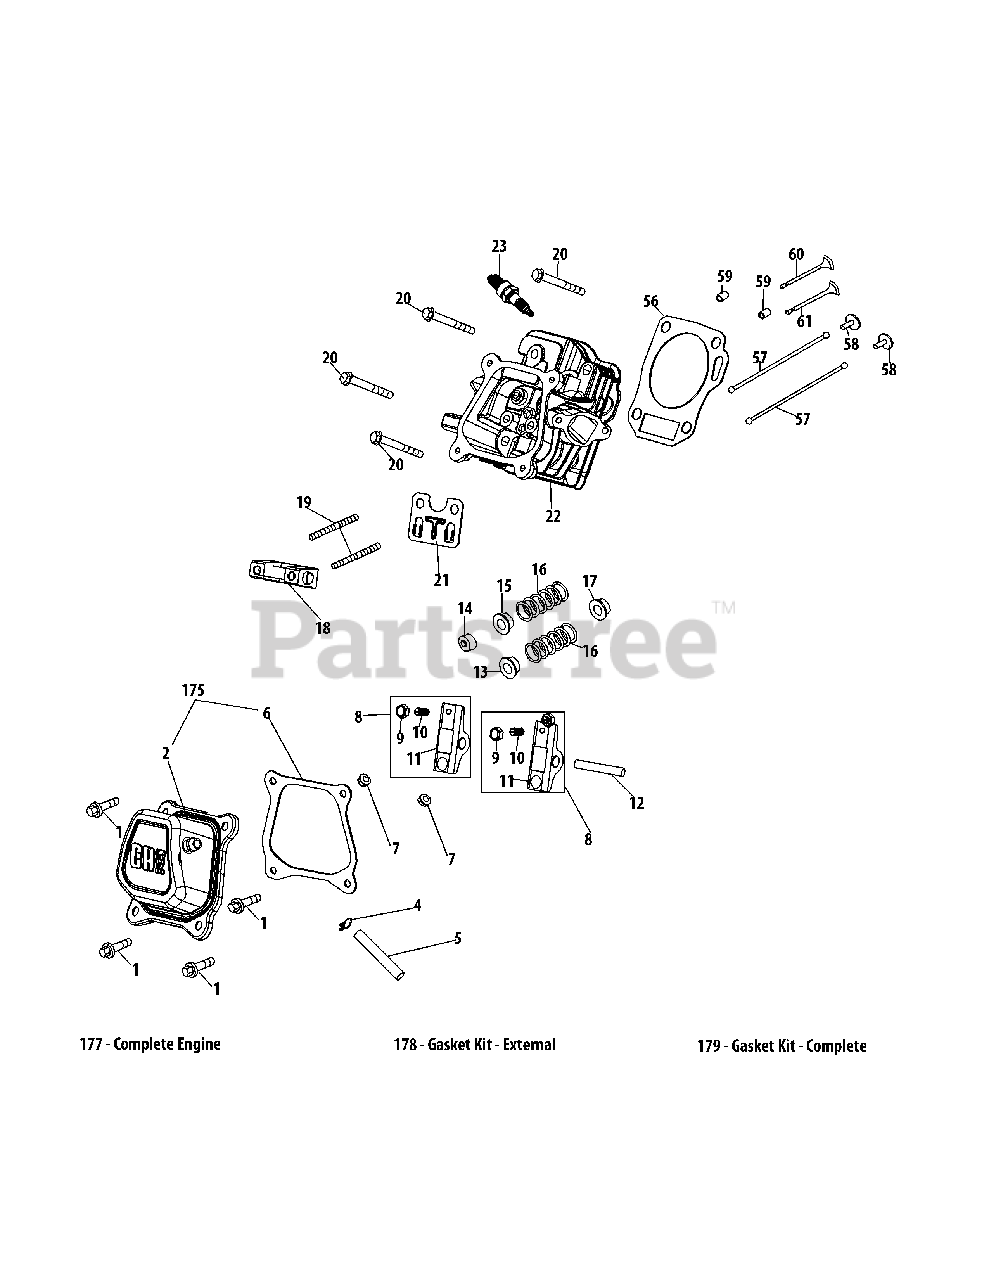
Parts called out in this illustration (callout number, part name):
1	Bolt M6×16
2	Valve Cover
4	Clamp, Fuel Hose
5	Breather Hose
6	Valve Cover Gasket
8	Rocker Arm Assembly
9	Valve Clearance Adjustment Screws
10	Adjust Nut
11	Rocker Arm
12	Rocker Arm Pivot Shaft
13	Valve Spring Retainer (Intake)
14	Exhaust Lash Cap
15	Valve Spring Retainer (Exhaust)
16	Valve Spring
17	Valve Seal (Intake)
18	Rocker Arm Pivot Block
19	Bolt, Pivot
20	Bolt M10×1.25×60
21	Push Rod Guide
22	Cylinder Head Assembly
23	Spark Plug/F6Rtc
56	Gasket, Cylinder Head
57	Kit-Push Rod
59	Dowel Pin 12×16
175	Valve Cover Kit
177	Complete Engine
178	Gasket Kit - External
179	Gasket Kit - Complete
